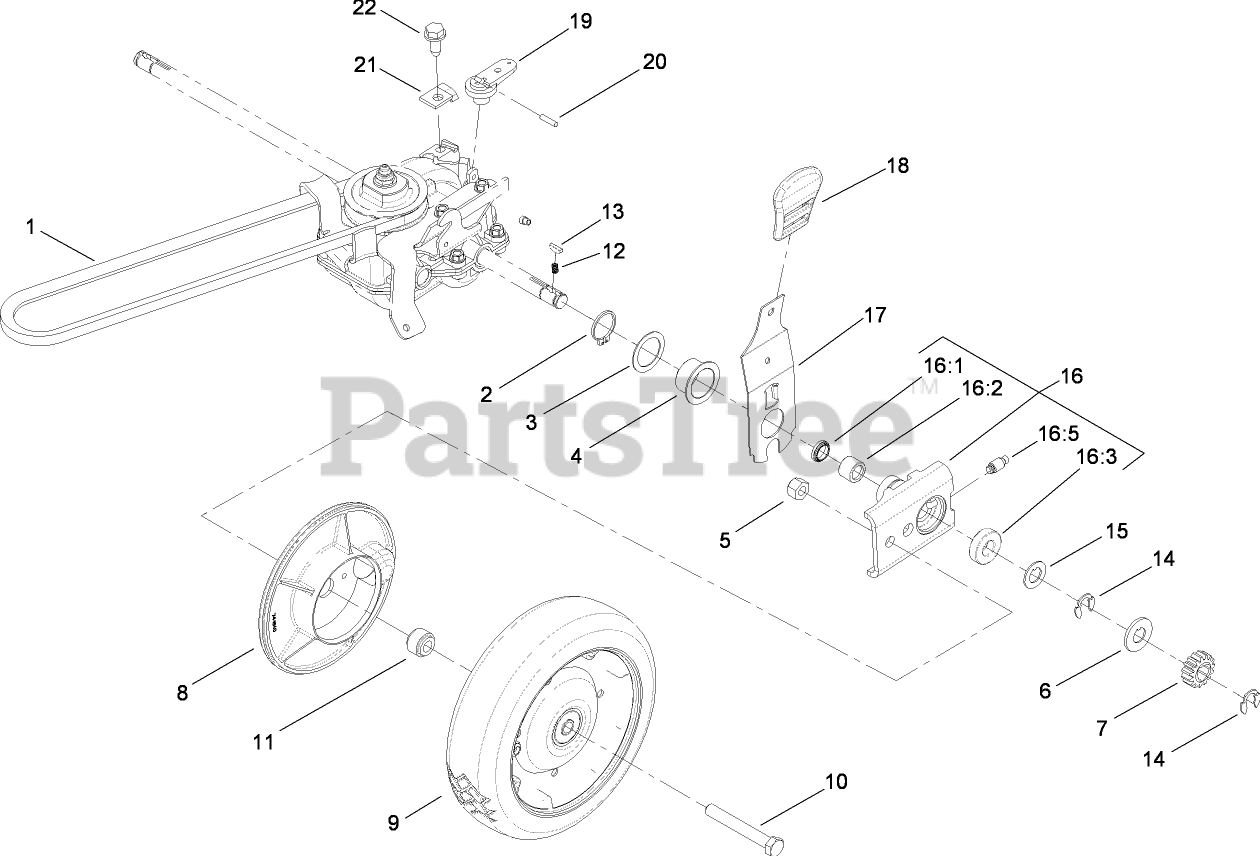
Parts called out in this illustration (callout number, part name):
1	V-BELT
2	RING-RETAINING
3	WASHER
4	BUSHING-FLANGE
5	NUT-LOCK, CONE
6	WASHER-THRUST, OUTER
7	GEAR-PINION
8	COVER-WHEEL
9	WHEEL AND TIRE ASM
10	SCREW-HH
11	SPACER-COVER, WHEEL
12	SPRING-COMPRESSION
14	RING-RETAINING
15	WASHER-THRUST, OUTER
16	PIVOT ARM ASM
16:1	SEAL-OIL
16:2	BEARING-ROLLER
16:3	BEARING-WHEEL
17	REAR SPRING ARM ASM
18	KNOB-HOC
19	LEVER-SHIFT
20	PIN-COIL
21	CLAMP-CABLE
22	SCREW-HWHTF
